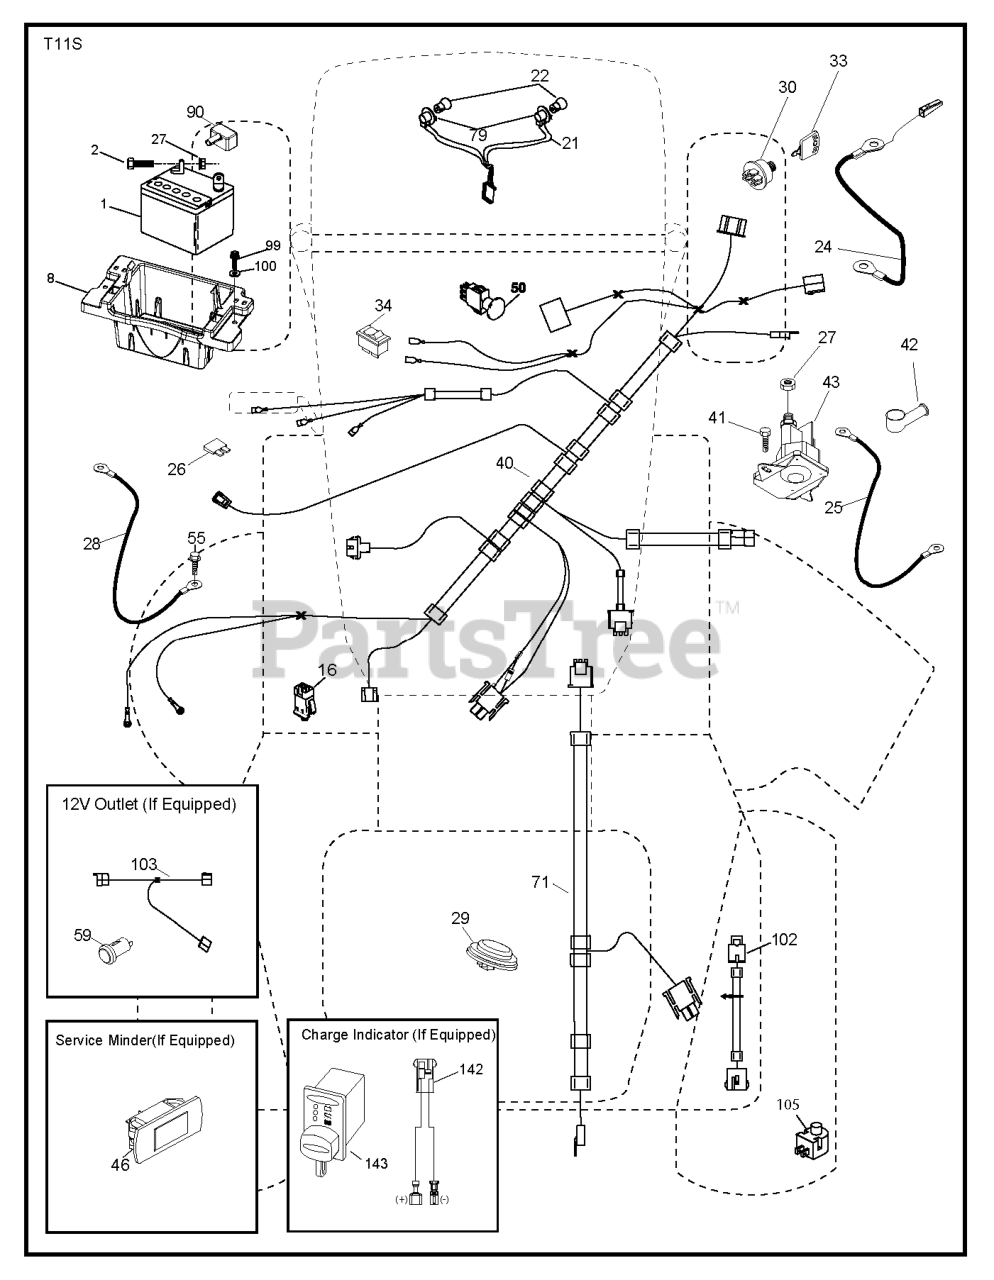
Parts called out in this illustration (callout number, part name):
1	Battery 12 Volt 25 Amp
2	BOLT.HEX.1/4.X.3/4.DICHROMATE
8	TRAY.BATTERY BOX.FRONT
16	SWITCH INTERLOOK PUSH-IN
21	HARNESS.LIGHT W/4152J BULBS
24	CABLE.FRBATT.W/WIRE.8GA.8
25	CABLE.STARTER.8GA.17.5
26	FUSE 20AMP
28	CABLE.GROUND.21"BLK.8GA.90T
29	SWITCH.SEAT.DELTA.OPC.
30	SWITCH.IGN.DELTA.W.LGH.ROS
33	KEY.CHAIN.BLISTER.PACK.GEN.USA
33	KEY.CHAIN.BLISTER.PACK.GEN.INT
40	HARNESS HARNESS..DASH.ING.ELEC
41	SCREW
42	TERMINAL COVER
46	GUAGE.SRVCMNDR.HRMTR.
50	SWITCH.PTO.8TERMINAL.STD.BLK
50	RP SWITCH.PTO.TERMINAL.STD.RED
55	SCREW 5/16"
71	HARNESS-CHASSIS SUB
79	BULB HOLDER ASM.
90	COVER.TERMINAL.BATTERY
99	SCREW HEXWSHR 1/4-20X3/4
102	HARNESS PIGTAIL PCH TEX ROS
105	REVERSE SWITCH
